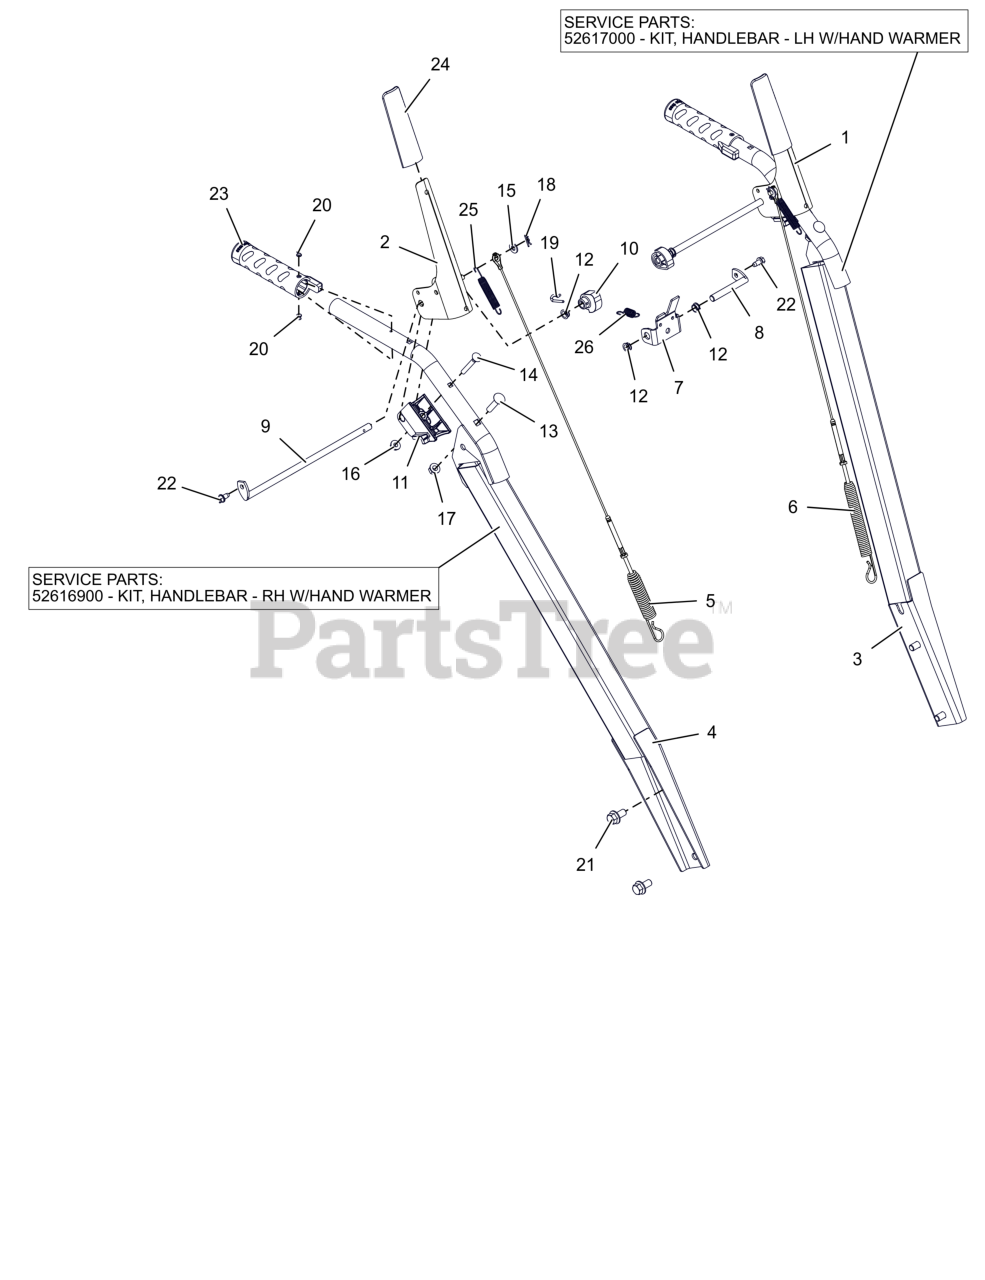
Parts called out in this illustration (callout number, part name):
1	LEVER, CLUTCH-LH
2	LEVER, CLUTCH-RH
3	HANDLEBAR, HEAVYDUTY-PRO LH
3	KIT, HANDLEBAR-LH W/WARM GRIP
4	HANDLEBAR, HEAVYDUTY-PRO-RH
4	KIT, HANDLEBAR-RH W/WARM GRIP
5	CABLE, AUGER (DELUXE & PRO)
6	CABLE, UPPER TRACTION
7	BRACKET, INTERLOCK ARM
8	ROD, PIVOT - INTERLOCK
9	ROD, PADDLE MOUNT - PRO
10	CAM, INTERLOCK
11	BLOCK, CLUTCH PADDLE
12	BUSHING, POLYLINER-.38 SNAPIN
13	BLT,RHSN .31-18X1.50 G5 ZCC
14	BLT-RDHDXLSQNK .25-20X2.0 G5YZ
15	WSHR,FLT .281X.625X.065 ZCC
16	NUT-LK-CTR-FLG .25-20 ZC120
17	NUT-LK-TOP-FLG .312-18 GF ZCC
18	PIN, HAIR #178 .06X.77 ZCC
19	PIN, SPRING CLIP
20	RVT-POP #43 .125X.313 STL ZINC
22	SCR-TAP .25-20X.50 HWH ZCC
23	GRIP- HEATED HANDLE - BLACK
24	SLEEVE- CLUTCH PADDLE
25	SPRING, EXTENSION
26	SPRING-EXT .047X.438X1.45
